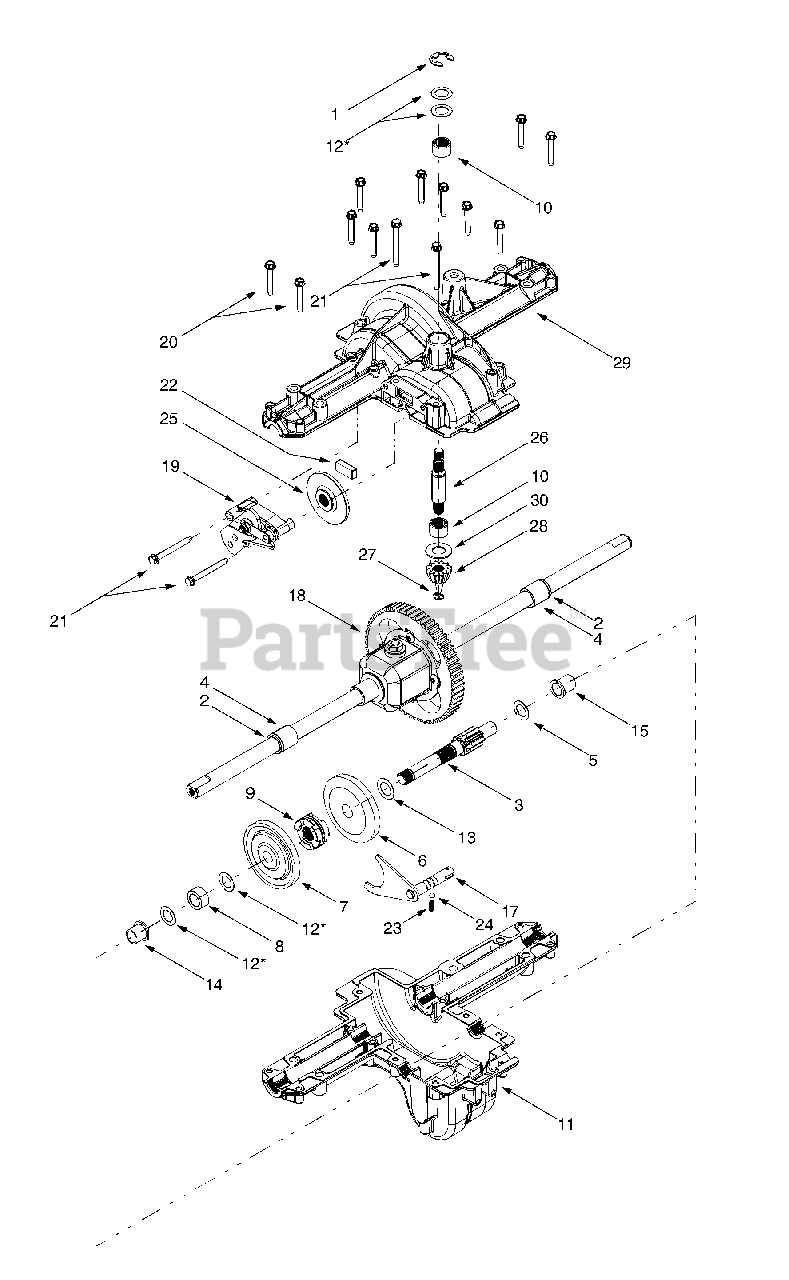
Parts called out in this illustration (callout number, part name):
2	Seal, .75 x 1.0 x .125
4	Sleeve Bearing, .75 x .1.0 x 1.0
5	Thrust Washer, 1.0 x .632 x .0
6	42-tooth Bevel Gear
7	42-tooth Bevel Gear
8	Spacer, .633 x 1.0 x .513
9	Clutch Collar
10	Needle Bearing, .625 x .875
11	Lower Housing
13	Flat Washer, .70 x 1.125 x .031
14	Flange Bearing, 5/8 x 3/4 x 3/4
15	Flange Bearing, 5/8 x 3/4 x 15/16
17	Detent Shaft Assembly
18	Differential Assembly
19	Brake Assembly
20	Self-tapping Screw, 1/4-20 x 1.625
21	Self-tapping Screw, 1/4-20 x 2.375
22	Brake Pad
23	Compression Spring
27	Retaining Ring, .437
28	14-tooth Bevel Pinion
29	Upper Housing
30	Thrust Washer, .635 x 1.25 x .042
